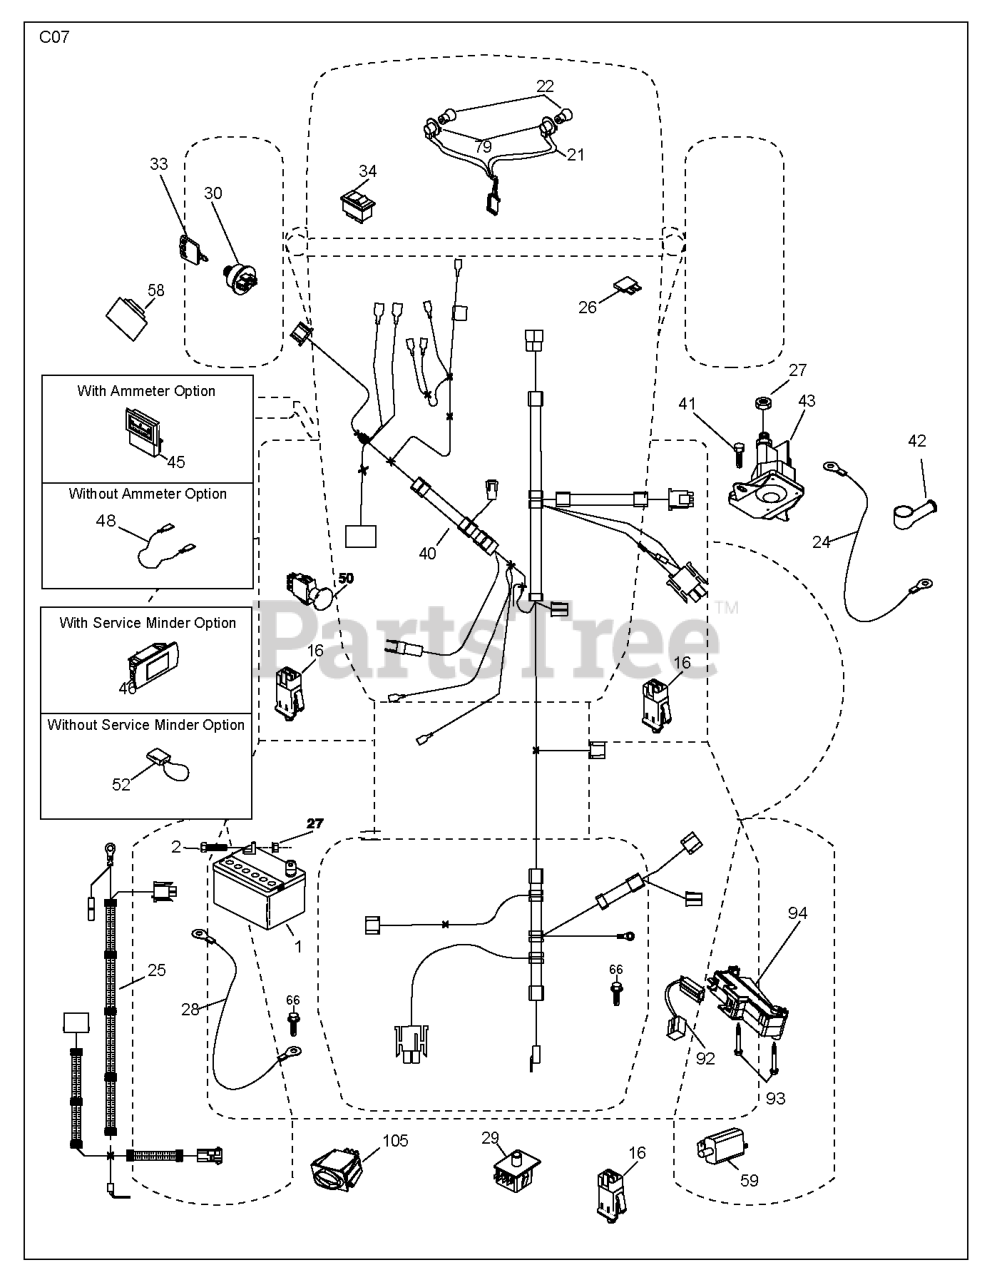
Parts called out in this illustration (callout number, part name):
1	Battery 12 Volt 25 Amp
2	BOLT.HEX.1/4.X.3/4.DICHROMATE
16	SWITCH INTERLOOK PUSH-IN
21	HARNESS.LIGHT W/4152J BULBS
25	CABLE.STARTER.6GA.11"RED
26	FUSE 20AMP
27	NUT
28	CABLE GROUND
29	SWITCH.SEAT.DP W/RAMPS
30	SWITCH.IGN.DELTA.W.LGH.ROS
33	KEY.CHAIN.BLISTER.PACK.GEN.USA
41	BOLT
42	TERMINAL COVER
43	SOLENOID.W/BRASS.PLUNGER
46	RP.GUAGE.SRVCMNDR.HRMTR.
48	ADAPTER.AMMETER
50	RP.PTO.SWITCH.8 TERMINAL.BLACK
58	BUZZER
59	.WITCH.FULL BAGGER.INDICATOR
79	BULB HOLDER ASM.
92	HARNESS.PIGTAIL.CONSLE
93	SCREW.PLASTITE
94	MODULE.REVERSE.ROS
